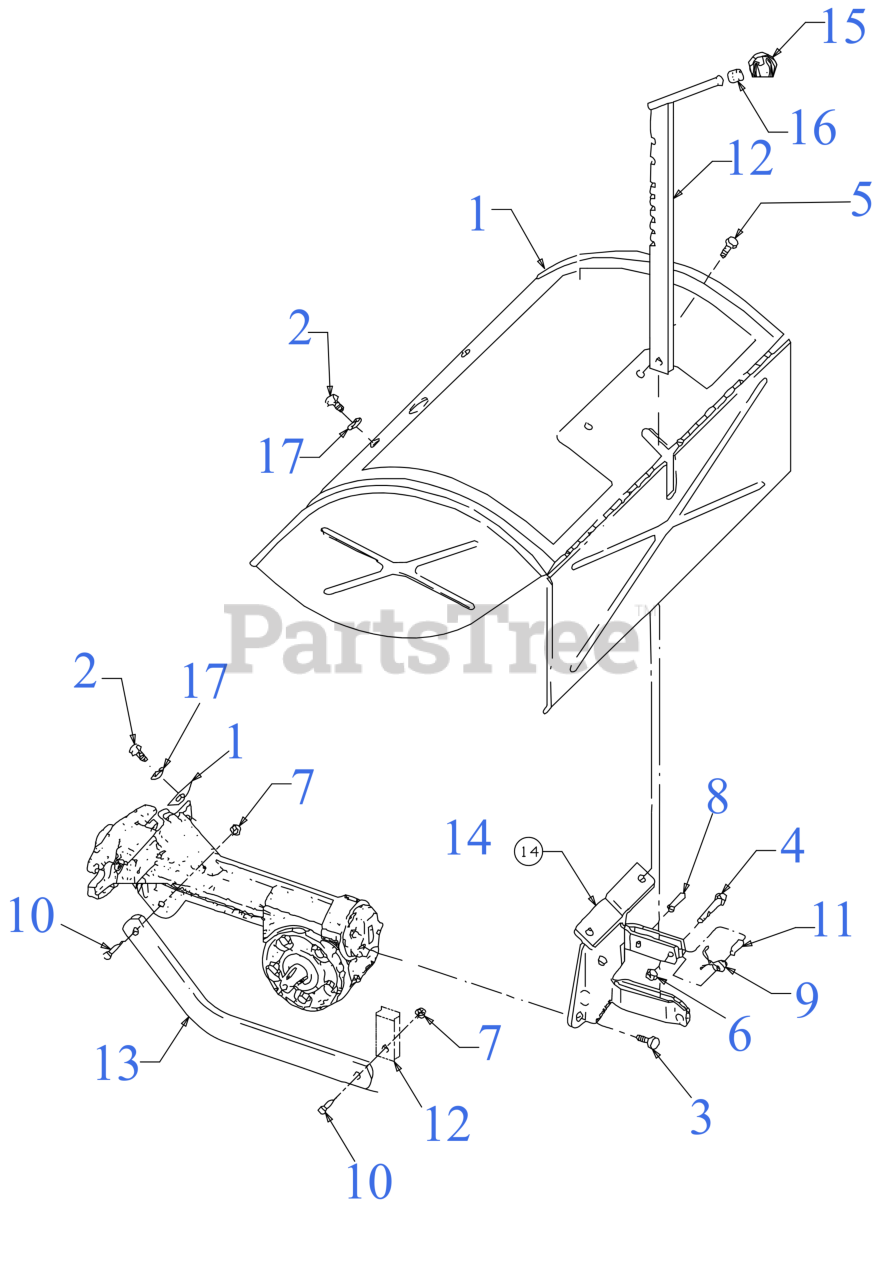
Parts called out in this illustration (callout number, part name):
1	TINE HOOD ASSEMBLY WITH FLAP
2	SCREW 5/16-18
3	HEX SCREW 5/16-18 x .625 GR5
4	SCREW 1/4-20 X1.00 GR5
5	SCREW 1/4-20 X.500
6	FLANGE LOCK NUT
7	LOCK NUT 3/8-16
9	TORSION SPRING
10	SHOULDER SCREW .498 DIA x .340
11	SPLIT SPACER
12	BAR DEPTH REGULATOR
13	DEPTH REGULATOR BAR
14	BRACKET-HOOD
15	CONTROL KNOB
16	RING-TOLERANCE
17	WASHER-#1.125X.344
